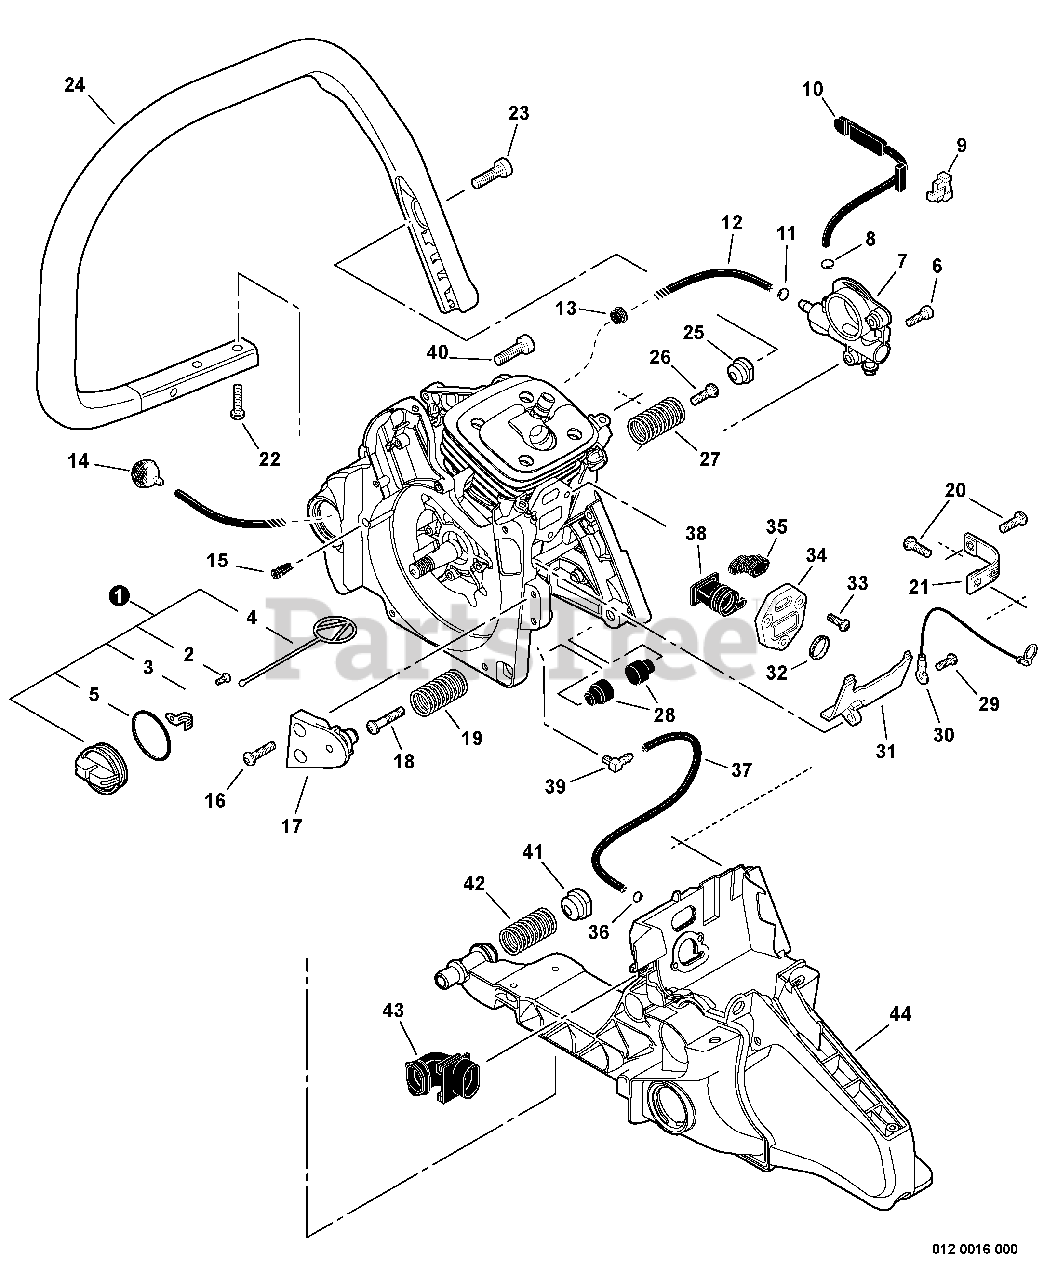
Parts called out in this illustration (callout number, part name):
1	CAP ASSY, OIL
2	SCREW, TAPPING 3×8
3	RETAINER, CONNECTOR
4	CONNECTOR, CAP L= 60 MM
5	O-RING 28
6	BOLT, TORX 4×12
7	AUTO-OILER ASSY
8	CLIP 6 MM
9	BRACKET
10	PIPE, OIL OUTLET
11	CLIP 6 MM
12	PIPE, FUEL 3×6×210 BLACK
13	GROMMET
14	FILTER, OIL
15	VENT ASSY
16	BOLT, TORX 5×20
17	HOLDER, SPRING
18	BOLT, TORX 5×20
19	SPRING, COMPRESSION
20	BOLT, TORX 5×16
21	STRAP, SAFETY
22	BOLT, TORX 5×20
23	BOLT, TORX 6×20
24	HANDLE, FRONT
25	HOLDER, SPRING Ø14.4
26	BOLT, TORX 5×16
27	SPRING, COMPRESSION Ø17×38.4×2.6
28	CUSHION
29	BOLT, TORX 5×16
30	LEAD - GROUND L= 170
31	GUIDE, AIR
32	COLLAR 16
33	BOLT, TORX 5×16
34	RETAINER, BELLOWS
35	BELLOWS, INTAKE
36	CLIP Ø6.5 MM
37	PIPE, FUEL 3×6×120 BLACK
38	BELLOWS, INTAKE
39	CONNECTOR, PIPE
40	BOLT, TORX 6×20
41	HOLDER, SPRING Ø17
42	SPRING, COMPRESSION Ø20×40×3.3
43	PIPE, AIR INTAKE
44	HANDLE, REAR
